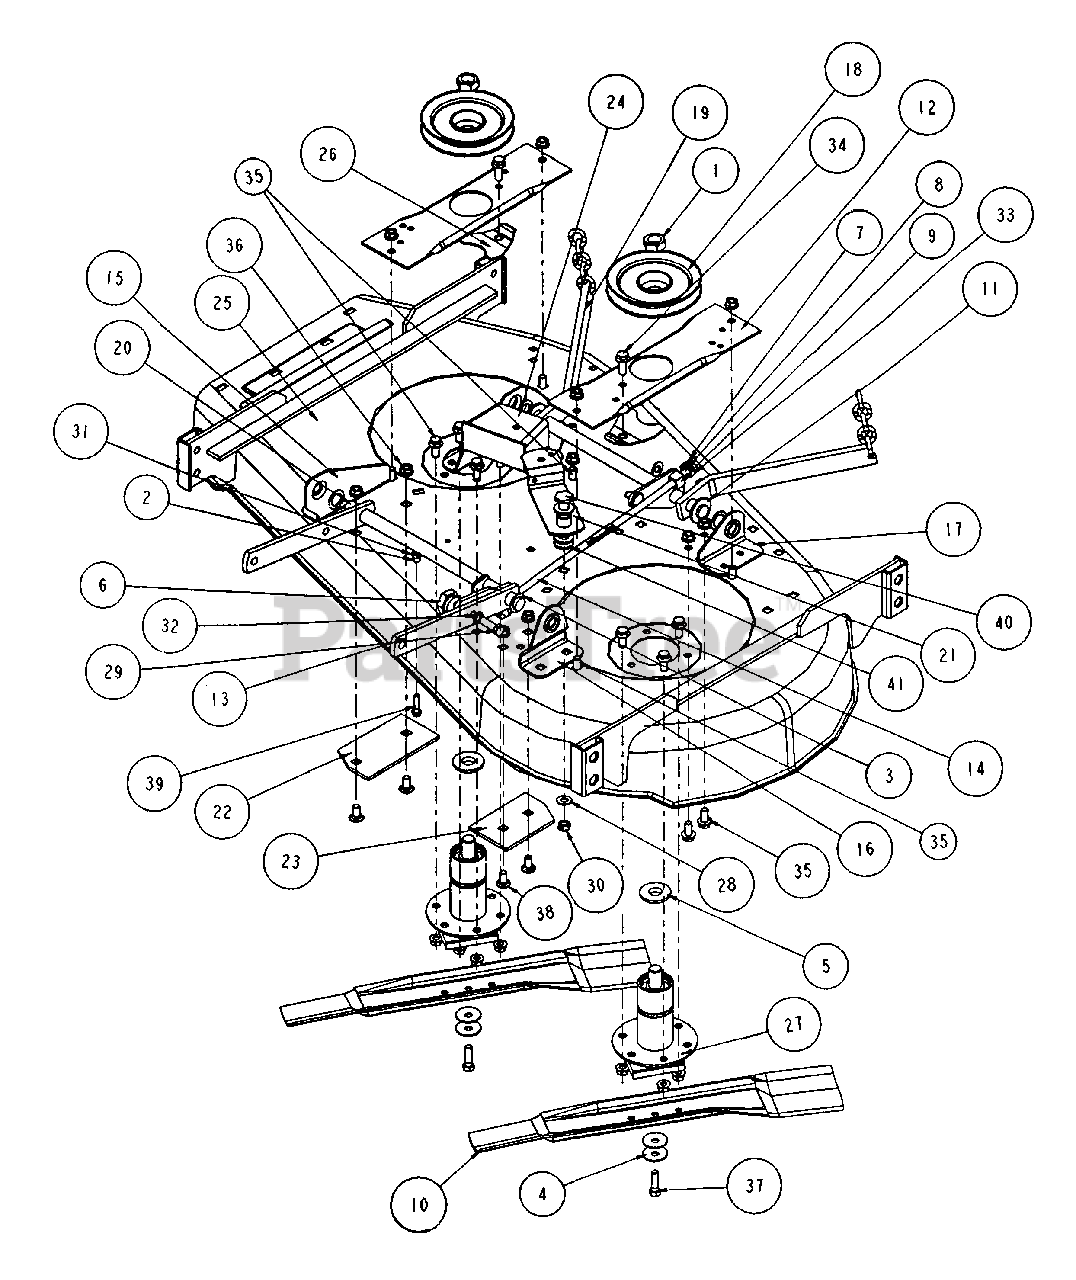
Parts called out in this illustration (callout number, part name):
1	NUT, 3/4-16 Hex Jam
2	SPACER, .26 x .3
3	WASHER, 3/4" x 1-1/8"
4	WASHER, Cone
5	WASHER, Spindle
6	ECCENTRIC, Leveling
7	HAIR PIN, #13
8	SPACER, MF1200
9	SWIVEL, Brake Link
10	BLADE, 21" Standard Lift
11	WASHER, 3/4 I.D. x 1-1/2" O.D. Flat
12	BRACE, Spindle
13	LIFT ARM, Front
14	ROD, Cutter Deck Timing
15	BRACKET, R.H. Front Lift, 42" Deck
16	BRACKET, L.H. Front Lift, 42" Deck
17	BRACKET, L.H. Rear Lift, 42" Deck
18	PULLEY, 5-1/4"
19	LIFT ARM, Rear
20	LIFT ARM, Front
21	IDLER ARM
22	REINFORCEMENT, R.H.
23	REINFORCEMENT, L.H.
24	IDLER, Stationary
25	Deck Weldment
26	Assembly, Spindle Lock
27	ASSEMBLY, Spindle Brake
28	WASHER, 3/8" Flat
29	SCREW, 3/8-24 x 1-1/4" Hex Head Cap
30	NUT, 3/8-24 Hex Center Lock
31	NUT, 1/4-20 Hex Center Lock
32	WASHER, 3/8 Internal Tooth Lock
33	NUT, 3/8-16 Hex Center Lock
34	BOLT, 3/8-16 x 1" Hex Flange Lock
35	BOLT, 3/8-16 x 3/4" Hex Flange Lock, Grade 5
36	NUT, 3/8-16 Hex Flange Lock
37	SCREW, 3/8-24 x 1-1/4" Hex Head Cap, Grade 5
38	BOLT, 3/8-16 x 3/4" Carriage
39	BOLT, 1/4-20 x 1-1/8, Grade 5
40	SHOULDER BOLT, 3/8-24 x 5/8"
41	WASHER, 1/2" I.D.x 1-1/16" O.D.
